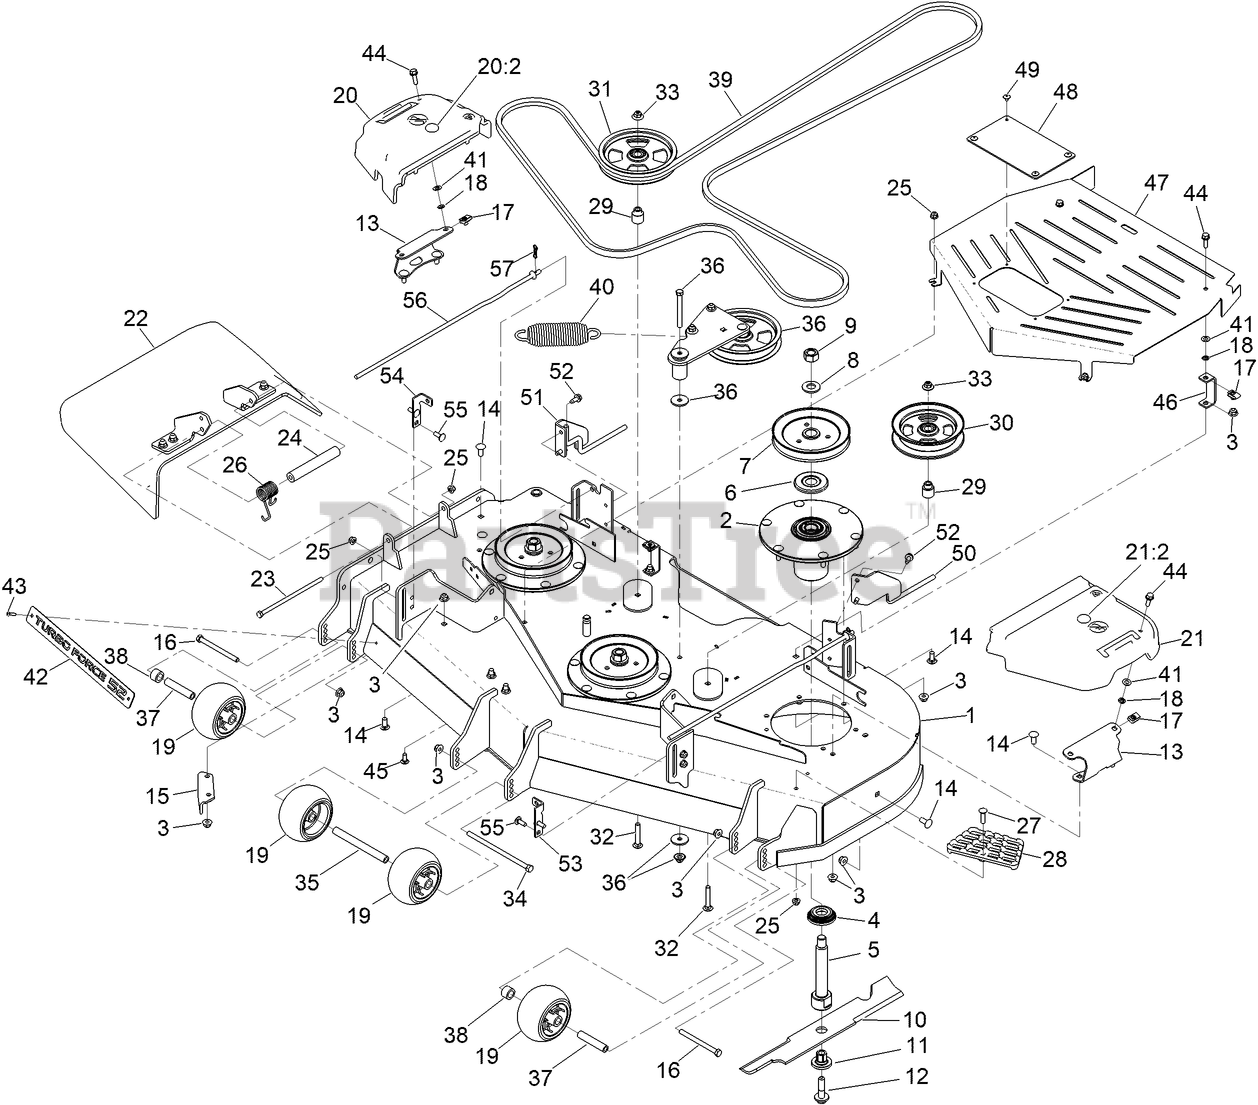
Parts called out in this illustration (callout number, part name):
1	DECK DECAL ASM
2	SPINDLE ASM
3	NUT-HF, NI
4	GUARD-BOTTOM
5	SHAFT-SPINDLE
6	GUARD-BEARING, TOP
7	SHEAVE-BLADE DRIVE 6.50
8	WASHER
9	NUT-HEX
10	BLADE-FLOW, HIGH
11	BUSHING-HEX
12	SCREW-SEMS
13	BRACKET-COVER, BELT
14	SCREW-CARR
15	BAFFLE-DISCHARGE
16	SCREW-HH
17	NUT-U
18	NUT-PUSH
19	ROLLER-SCALP, ANTI
20	RH BELT COVER ASM
20:2	PLUG-PLASTIC
21	LH BELT COVER ASM
21:2	PLUG-PLASTIC
22	RUBBER DEFLECTOR ASM
23	SCREW-HH
24	SPACER
25	NUT-HF, NI
26	SPRING-TORSION
27	SCREW-CARR
28	STEP-DECK
29	BUSHING, IDLER
30	PULLEY-IDLER, FLAT
31	PULLEY-IDLER, FLAT
32	SCREW-CARR
33	NUT-FLANGE, NI
34	SCREW-HH
35	SPACER-WHEEL
36	IDLER ARM ASM
37	TUBE-SHAFTING
38	TUBE-SPACER
39	BELT-V
40	SPRING-EXTENSION
41	WASHER-THRUST
42	PLATE-TURBO FORCE [BLACK]
43	RIVET-TRIFOLD
44	SCREW-HHF
45	SCREW-CARR
46	BRACKET-GUARD
47	GUARD-CENTER BELT 52
48	SHIELD-RUBBER
49	RIVET-POP
50	SUPPORT-LOWER LH
51	SUPPORT-LOWER RH
52	SCREW-HWHTF
53	BRACKET-SUPPORT, LH
54	BRACKET-SUPPORT, RH
55	BOLT-CARR
56	ROD-SKIRT, LOWER
57	PIN-COTTER, LOCKING
